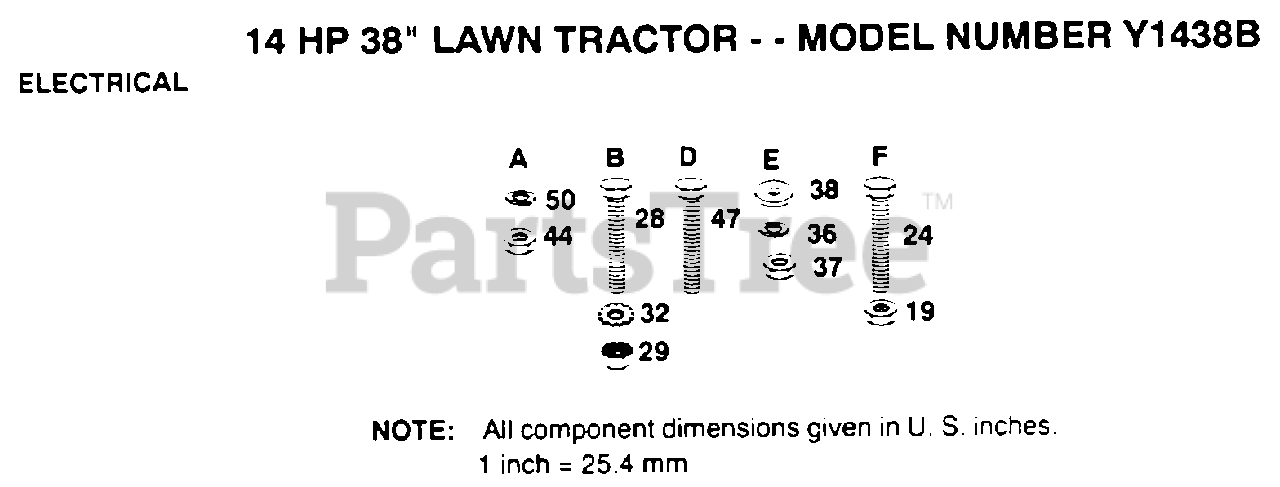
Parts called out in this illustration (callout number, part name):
24	BOLT
28	BOLT
29	NUT
38	WASHER
44	NUT
47	SCREW
